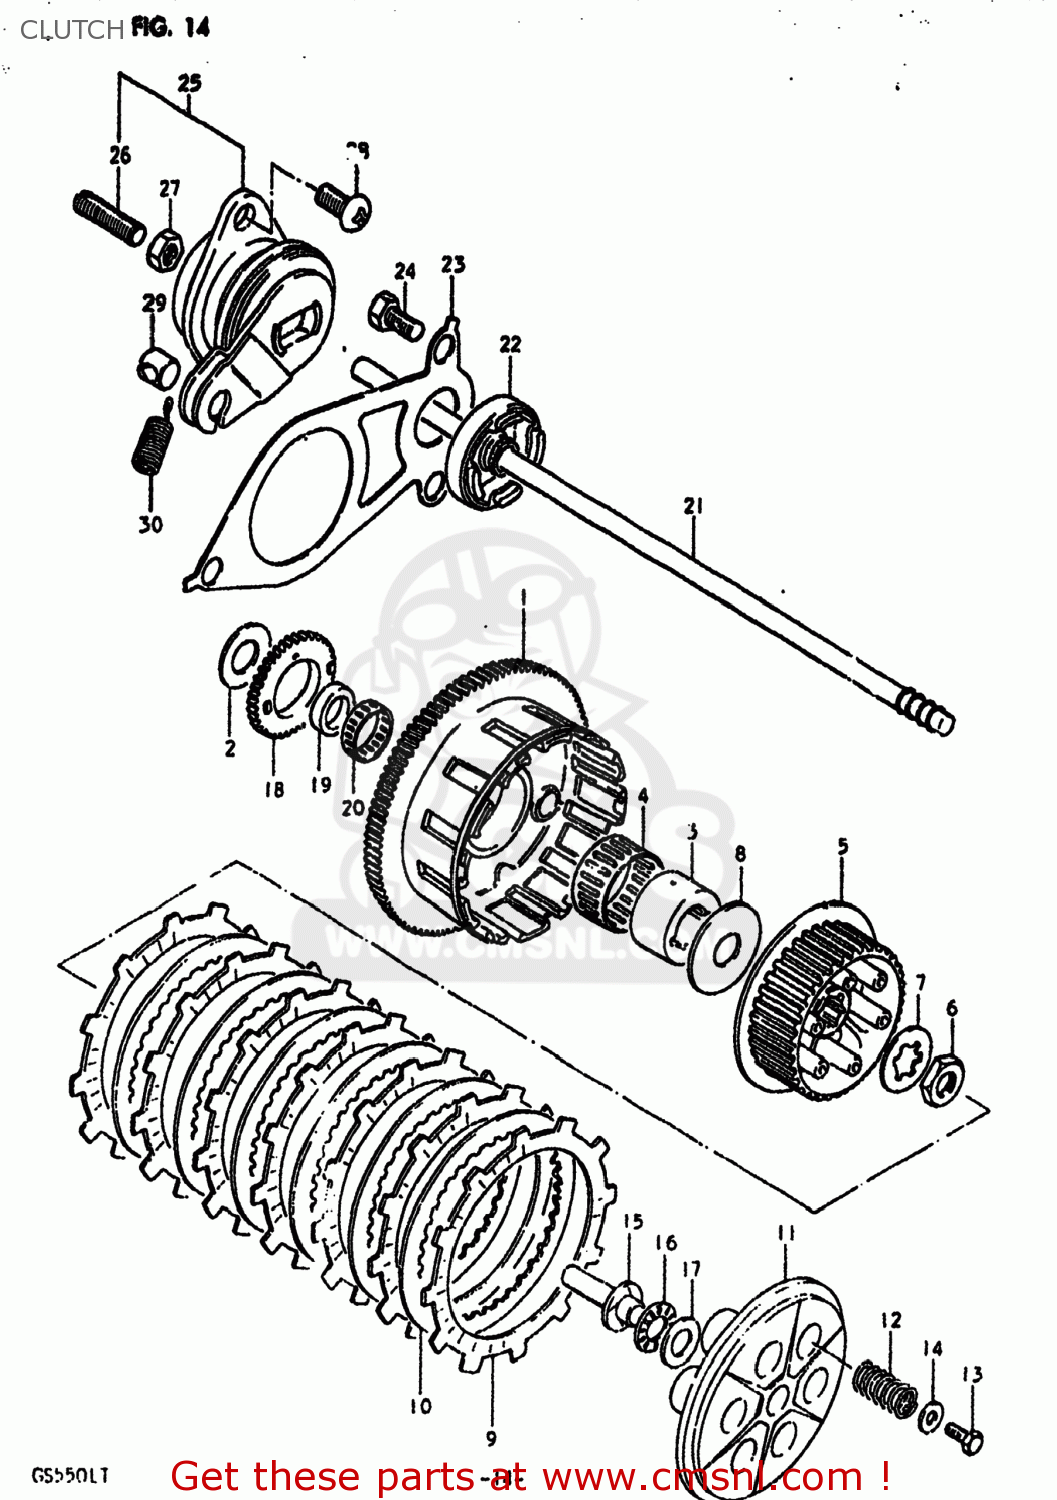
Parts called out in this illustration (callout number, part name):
1	GEAR ASSEMBLY,PRIMARY DRIVE NT:87
2	WASHER
3	SPACER,PRIMARY DRIVEN
4	BEARING
5	HUB,CLUTCH SLEEVE
6	NUT
7	WASHER,LOCK
8	WASHER(25X66X3.5)
9	PLATE,CLUTCH DRIVE (NAS)
10	PLATE,CLUTCH DRIVEN (NAS)
11	DISC,CLUTCH PRESSURE
12	SPRING
13	BOLT, UPPER
14	WASHER
15	PIECE,CLUTCH PUSH
16	BEARING(15X28X2)
17	WASHER
18	GEAR,ENG OIL PUMP DRIVE(NT:38)
19	SPACER,OIL PUMP DRIVE GEAR
20	BEARING(36X40X10)
21	ROD,CLUTCH PUSH
22	OIL SEAL
23	PLATE,CLUTCH PUSH ROD
24	BOLT
25	SCREW ASSEMBLY,CLUTCH RELEASE
26	SCREW
27	NUT 6MM
28	SCREW 6X12
29	PIECE,RELEASE ARM END
30	SPRING
